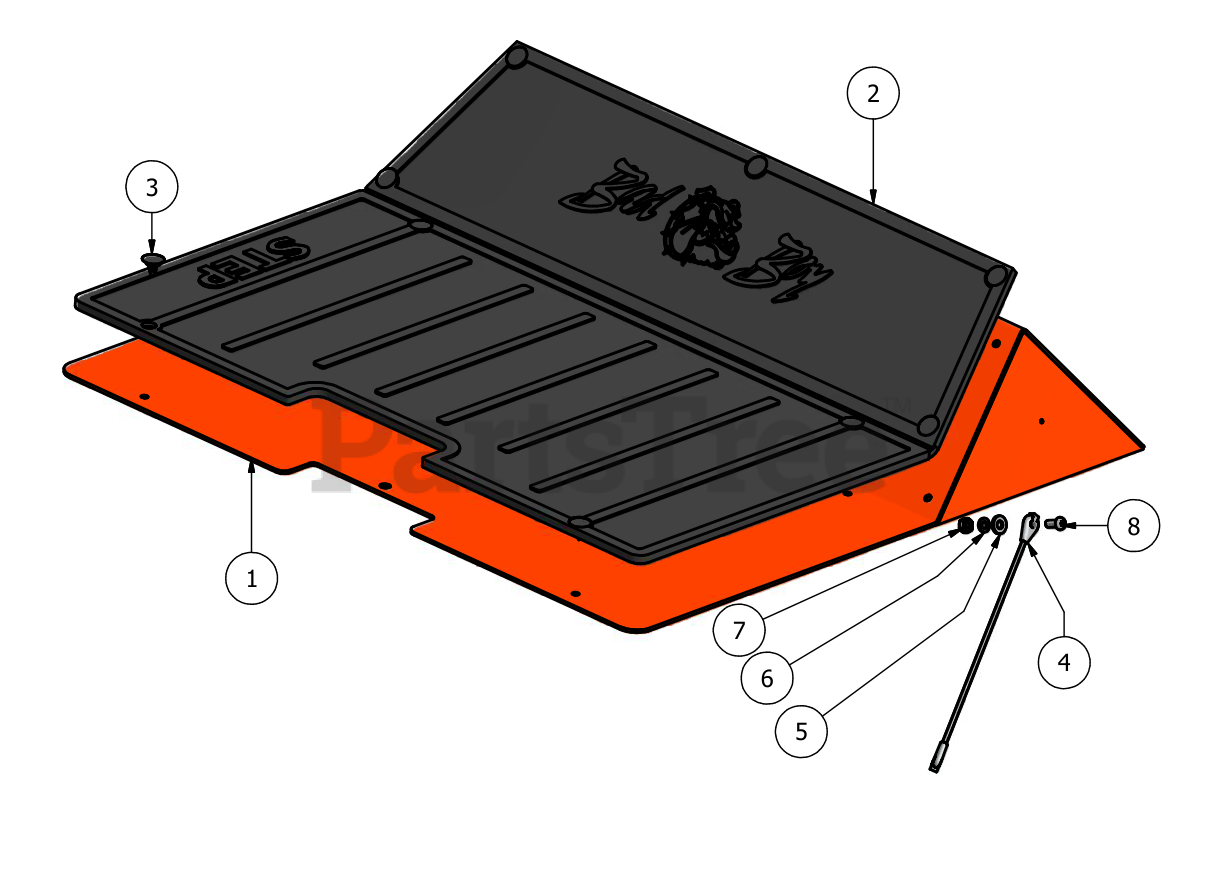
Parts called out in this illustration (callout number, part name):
1	2006 AOS Floor Panel
2	AOS Floor Mat
3	Ratchet Fastener
4	Floor Board Cable
5	1/4" Flat Washer
6	1/4" Lock Washer
7	1/4" Hex Nut
8	1/4" x 5/8" Buttonhead Bolt
